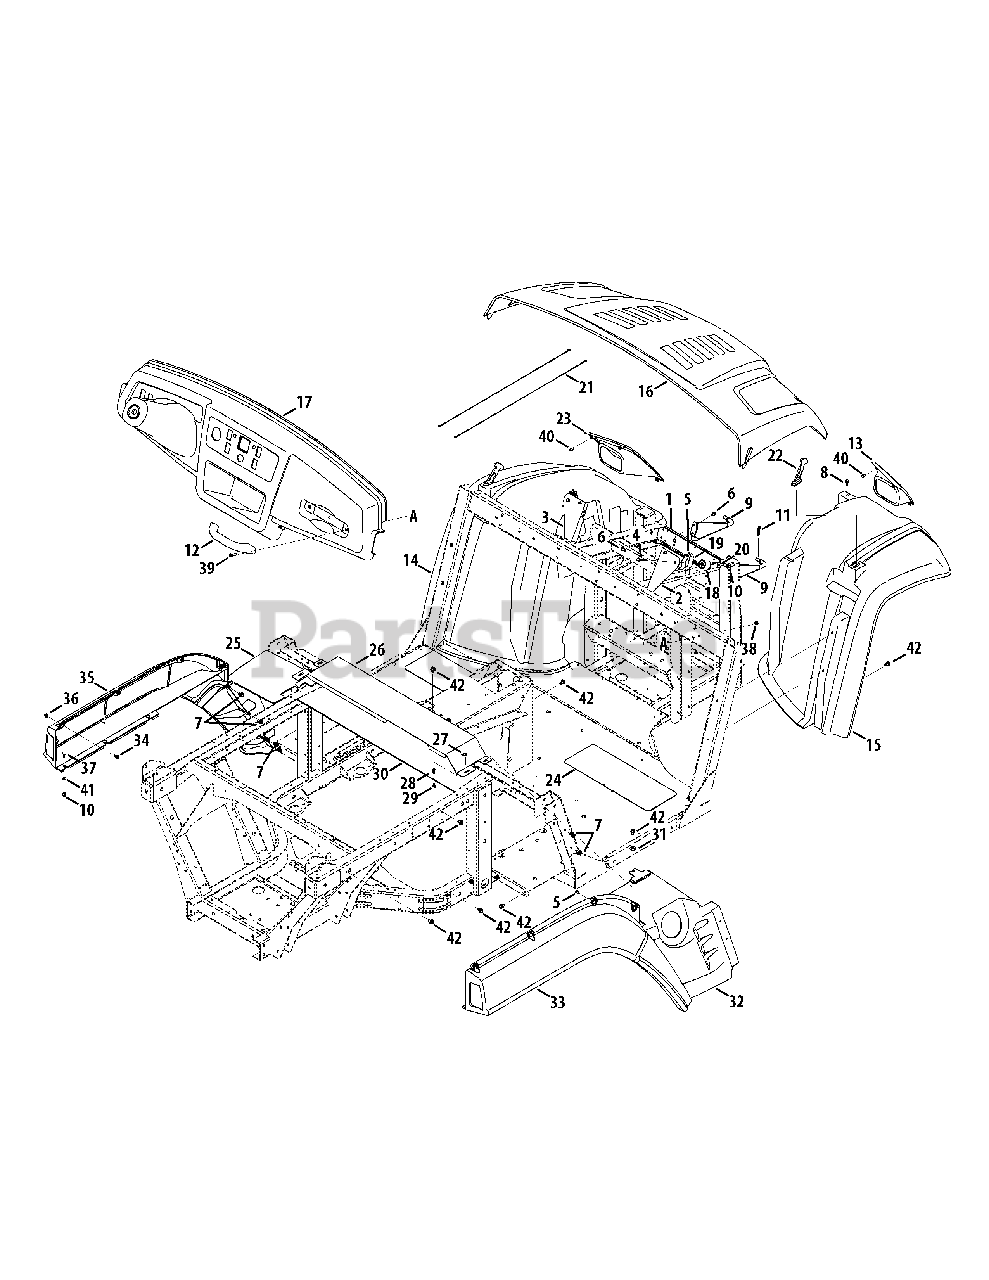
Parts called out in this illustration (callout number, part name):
1	Channel, Frame, Cross
2	Bracket, Hood/dash, Mount, Rh
3	Bracket, Hood/dash, Mount, Lh
4	Screw, 1/4-20, 1.75, Gr5, Std
5	Screw, #12-16 x .50
6	Screw, TT, 1/4-20 x .500
7	Screw, TT, 1/4-15 x .500
8	Hex Head Screw, 1/4-20 x 1.00
9	Rod Assembly, Hood Mount
10	Nut, Flange Lock, 1/4-20
11	Cotter Pin, Internal .08 x 1.42
12	Handle, W/Screw 400/500 S
13	Head Light RH
14	Fender, Lh 4x4
15	Fender, Rh 4x4
16	Hood, 4x4, Red
17	Dash, Uv 4x4
18	Roller, Latch, Hood
19	Spring, Latch, Hood
20	Washer, Flat, .283 x .75 x .030
21	Cable, Hood
22	Strap, Hood
23	Head Light LH
24	Pad, abrasive, toe plate (4x4)
25	Fender, Lwr Lh Rr
27	Latch, Panel, 1/4 Turn
28	Spring, Comprs, .40 OD x .040
29	Spring, Clip
30	Insulator, Cover, UV
31	Washer, Bell, .340 x .872 x .060
32	Fender, Lower Rh Rr
33	Fender, Rh Rr
34	Shldr Screw, .280 x .310, 1/4-20
35	Fender, Lh Rr
36	Nut, Acorn, 1/4-20
37	Screw, Crg, 1/4-20, .62, Gr2
38	Nut, Hex Lock., 1/4-20
39	Screw, Machine, 1/4-20 x 1.00
40	Screw, Tt, 1/4-20 x .625, Hxind.
41	Washer, Flat 1/4"
42	Screw, tt, 5/16-18 x 0.750
